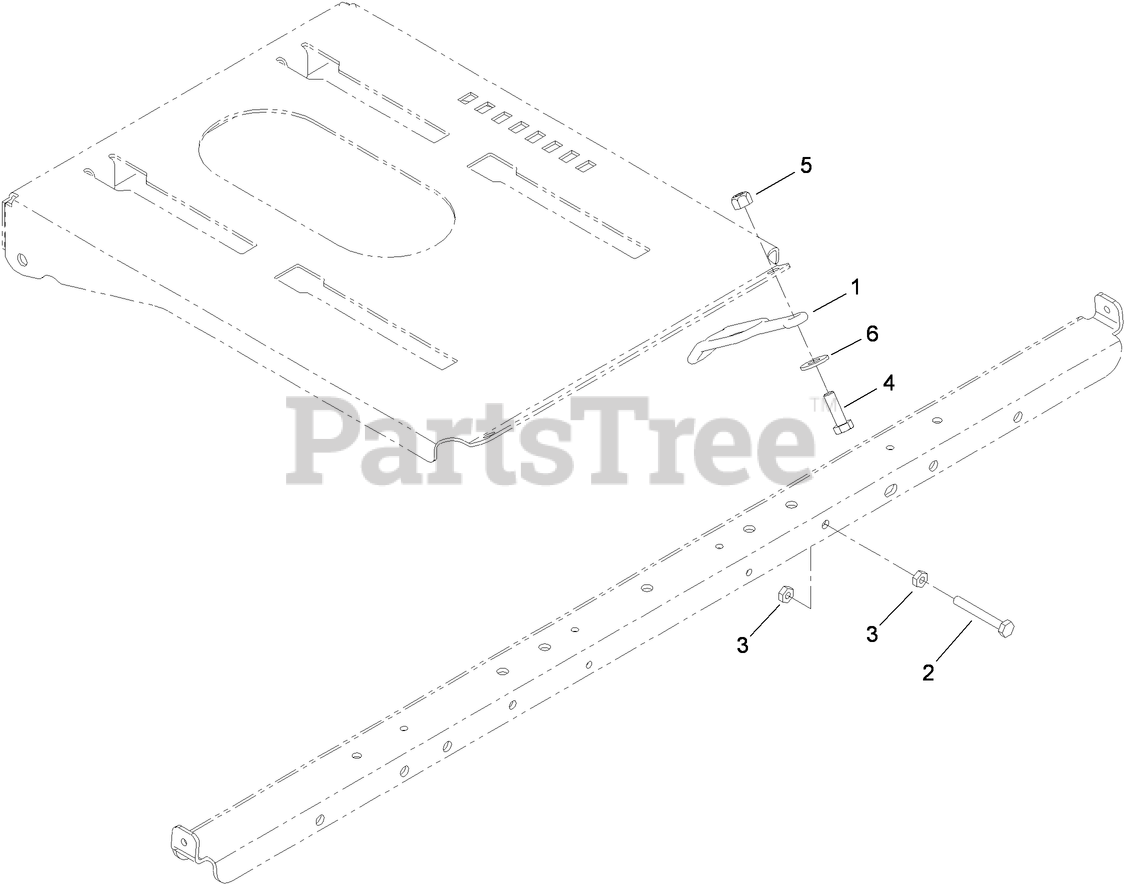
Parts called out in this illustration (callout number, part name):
1	RETAINER-DUCT
2	SCREW-HH
3	NUT-JAM
4	SCREW-HH
5	NUT-LOCK, NI
6	WASHER-FLAT
